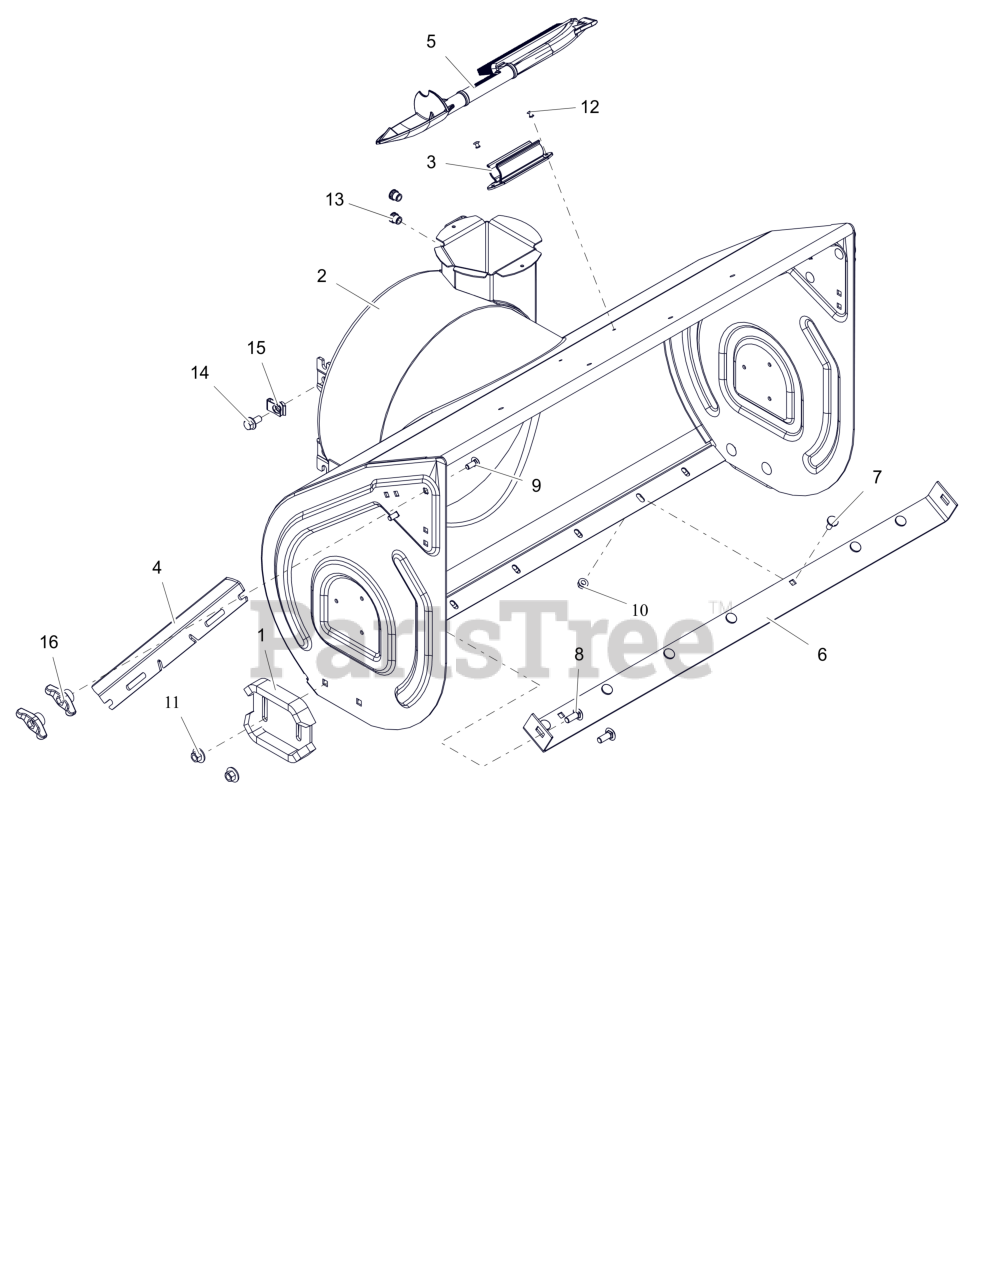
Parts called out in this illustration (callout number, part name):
1	RUNNER, SKID SHOE
2	HOUSING, BLOWER 36" W/DECAL
3	MOUNT, SNOW CLEAN OUT
4	CUTTER, DRIFT
5	DEVICE, SNOW CLEAN OUT W/BRUSH
6	BLADE, SCRAPER-36"
7	BOLT, MODIFIED HEAD CARRIAGE
8	BLT,RHSSN .38-16X1.00 G5 ZCC
9	BLT, RHSSN.31-18X.750 G5 ZCC
10	NUT-LK-TOP-FLG .312-18 GF ZCC
11	NUT- CON-LN .375-16 ZC120
12	RVT, POP .1875 ZCC
13	NUT,THD,INSERT .38-16 ZC120
15	NUT-RTNR .375-16X.37
16	KNOB,WING .31-18 UNC NYL/TALC
